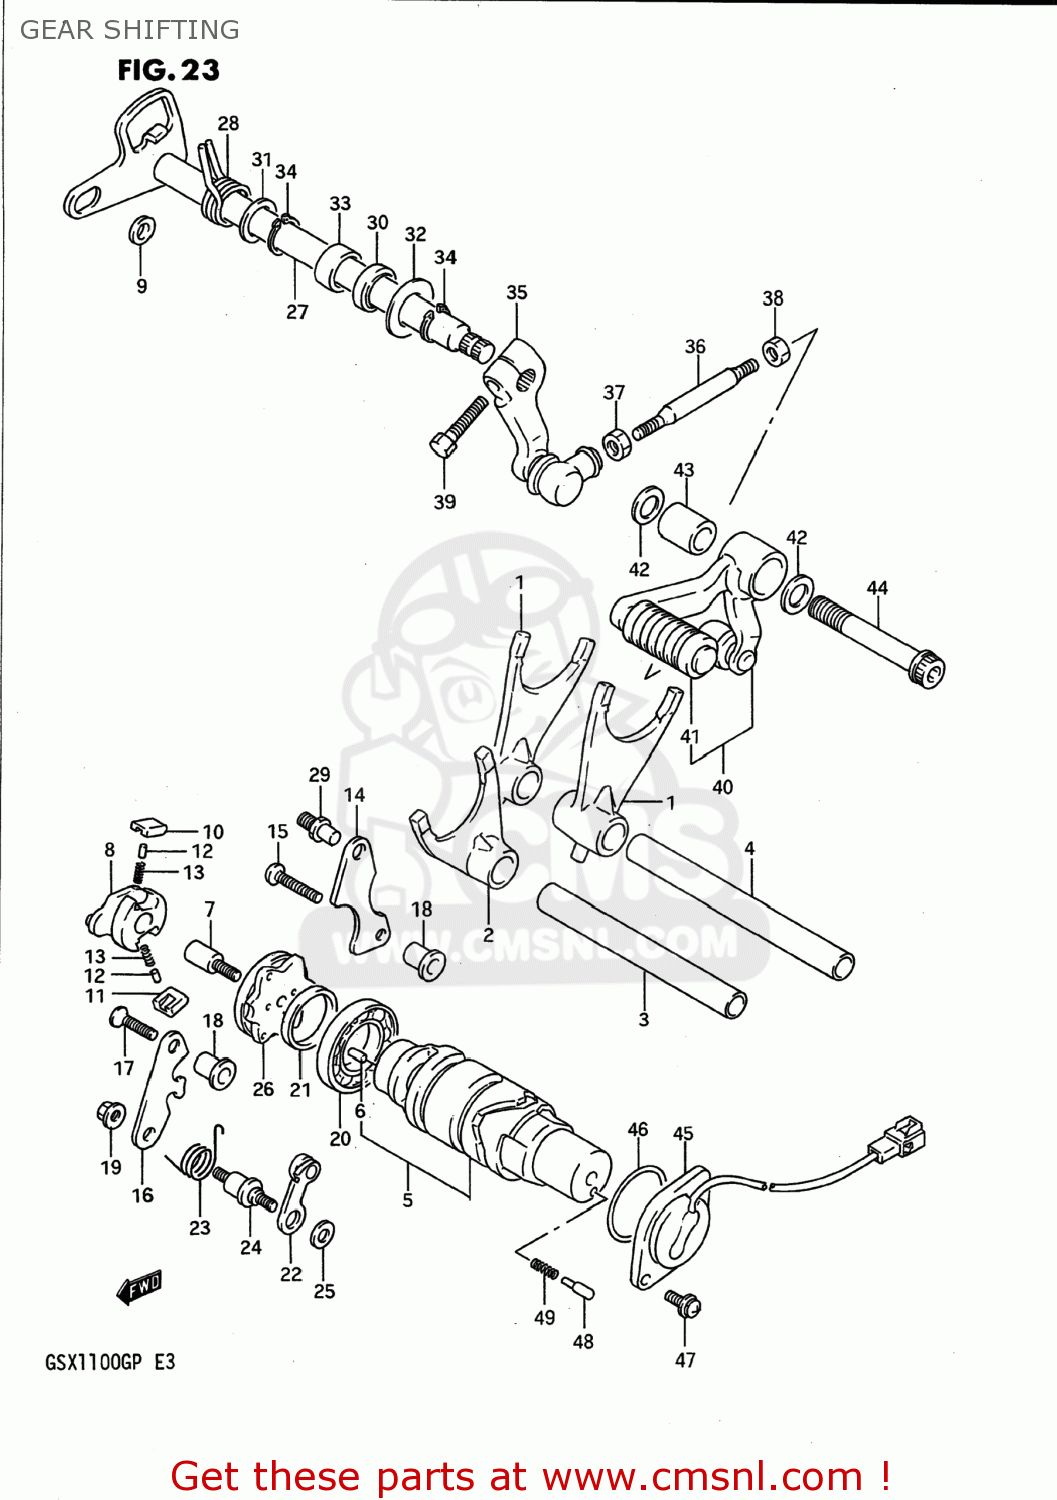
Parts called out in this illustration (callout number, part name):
1	FORK,GEAR SHIFT NO.1
2	FORK,GEAR SHIFT NO.3
3	SHAFT,GEAR SHIFT FORK
4	SHAFT,GEAR SHIFT FORK(L:128)
5	CAM COMP,GEAR SHIFT
6	PIN
7	PIN,SHIFT CAM DRIVEN GEAR
8	SHIFTER,GEAR SHIFT CAM
9	SPACER(7X10X5)
10	PAWL,GEAR SHIFT NO.1
11	PAWL,GEAR SHIFT NO.2
12	PIN(5X8)
13	SPRING
14	LIFTER,GEAR SHIFT PAWL
15	SCREW 6X30
16	GUIDE,GEAR SHIFT CAM
17	SCREW
18	SPACER(6.1X10X16)
19	NUT
20	BEARING
21	WASHER(25X32X3)
22	STOPPER,SHIFT CAM
23	SPRING,STOPPER ARM
24	SUPPORT,CAM STOPPER ARM
25	WASHER
26	PLATE,GEAR SHIFT CAM
27	SHAFT COMP,GEAR SHIFTING
28	SPRING
29	STOPPER,GEAR SHIFT CAM
30	SEAL,OIL(14X22X7.3)
31	WASHER,THRUST
32	WASHER
33	BEARING(14X20X12)
34	CIRCLIP
35	ARM,GEAR SHIFT LINK
36	ROD,GEAR SHIFT LINK
37	NUT
38	NUT 6MM
39	BOLT
40	LEVER ASSEMBLY,GEAR SHIFTING
41	RUBBER,GEAR SHIFT PEDAL
42	WASHER
43	SPACER(10X18X22)
44	BOLT
45	TERMINAL BASE ASSY,NEUTRAL
46	O RING(D:2.4,ID:36.5)
47	SCREW
48	PIN(5X15.5)
49	SPRING
